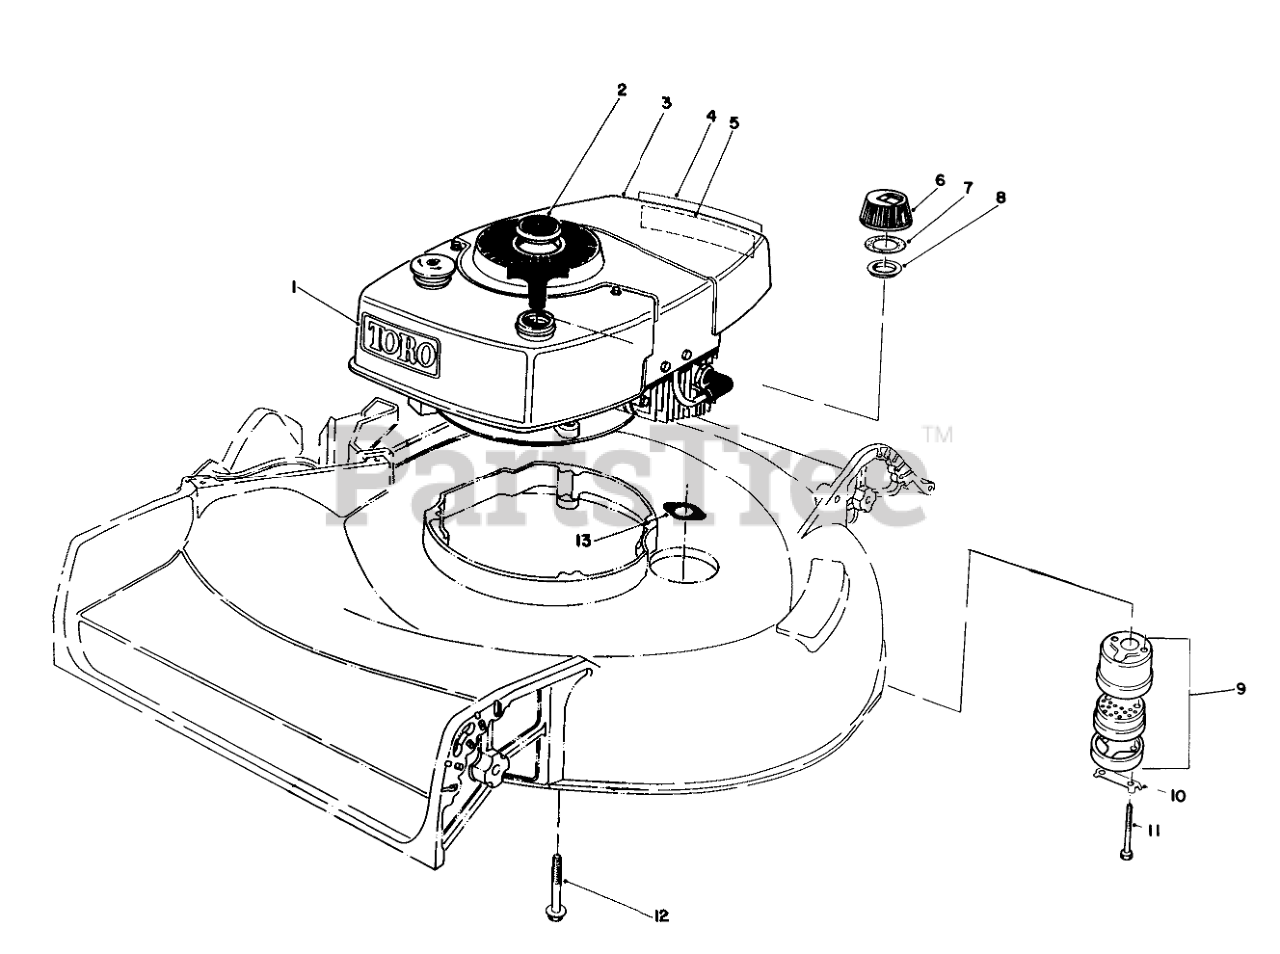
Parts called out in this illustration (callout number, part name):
1	Decal Tow
2	Plug Button
3	Engine
4	Decal-Primer
5	Decal Maintenance
6	Fuel Cap Assembly (Incl. Ref. #7 & 8)
7	GASKET
8	GAS CAP BAFFLE
9	Muffler Assembly (Incl. Ref. #10 & 11)
10	CLIP - LOCKING
11	SCREW-HH
12	3/8-16 X 2-3/4 CAPSCR
13	MUFFLER GASKET
